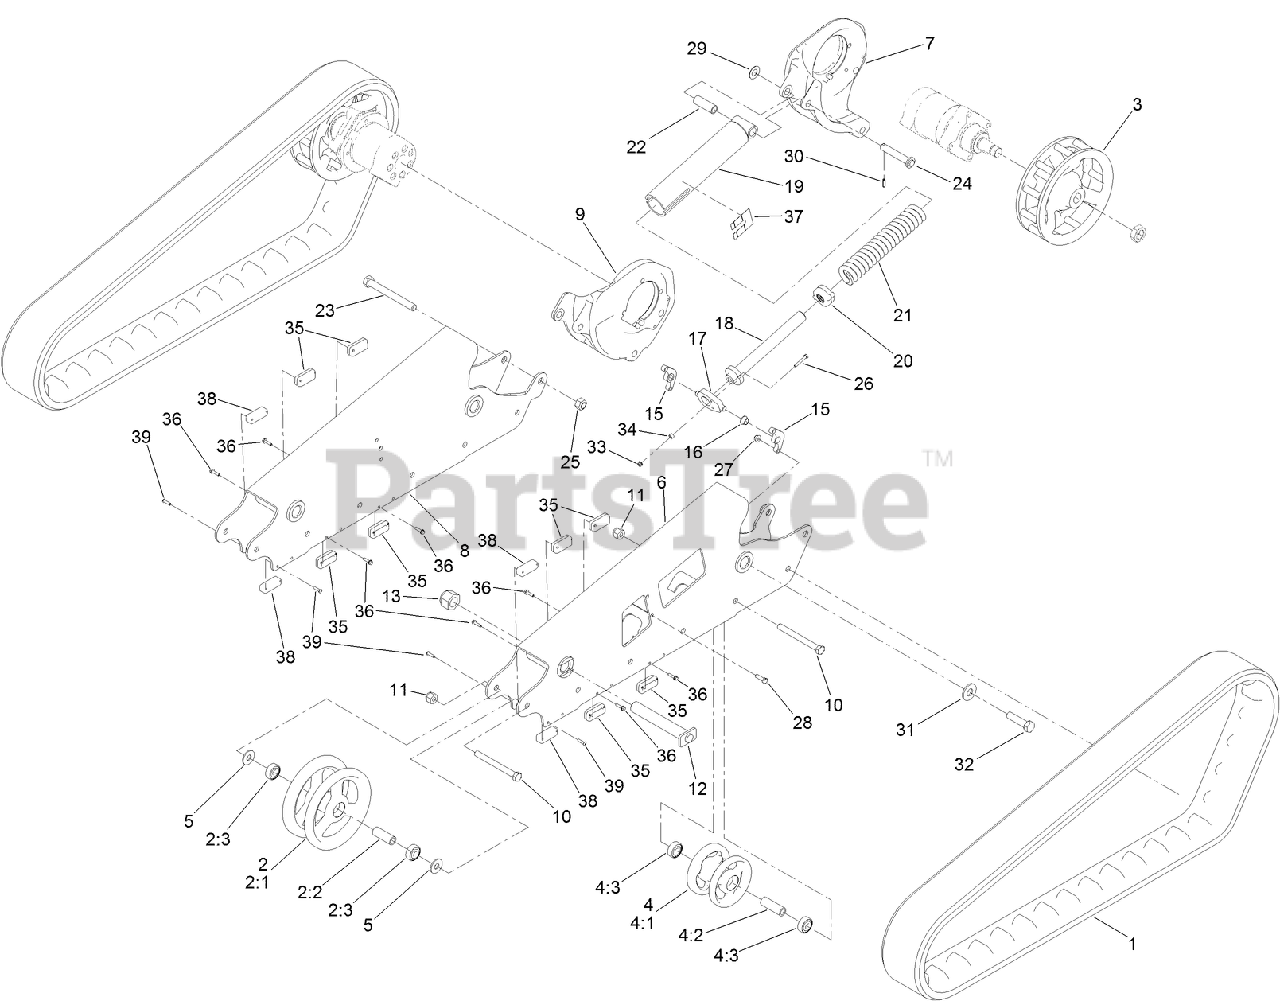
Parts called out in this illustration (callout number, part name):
2	TENSIONER WHEEL ASM
2:1	WHEEL-TENSIONER
2:2	SPACER-WHEEL, TENSIONER
2:3	BEARING-BALL
3	WHEEL-DRIVE
4	WHEEL ASM
4:1	WHEEL-ROAD
4:2	SPACER-WHEEL, ROAD
4:3	BEARING-BALL
5	WASHER-FLAT
6	MOUNT-NARROW WHEEL, LH
7	MOUNT-WHEEL, LH
8	MOUNT-NARROW WHEEL, RH
9	MOUNT-WHEEL, RH
10	SCREW-HH
11	NUT-HEX
12	PIN-TRACK
13	NUT-HH
15	PLATE-MOUNT, PIVOT
16	BUSHING-BELLCRANK
17	PLATE-PIVOT
18	BOLT-TENSIONER
19	PIVOT-TENSIONER
20	BLOCK-TENSIONER
21	SPRING-COMPRESSION
22	SPACER-PIVOT
23	SCREW-HH
24	PIN-TENSIONER
25	NUT-LOCK
26	SCREW-HH
27	NUT-HF, NI
28	SCREW-HH
29	WASHER-FLAT
30	PIN-SPRING
31	WASHER
32	SCREW-HH
33	NUT-HHF
34	SPACER
35	BLOCK-TRACK
36	SCREW-HFH
37	DECAL-INDICATOR, TENSIONER
38	BLOCK-TRACK
39	SCREW-HSBH
